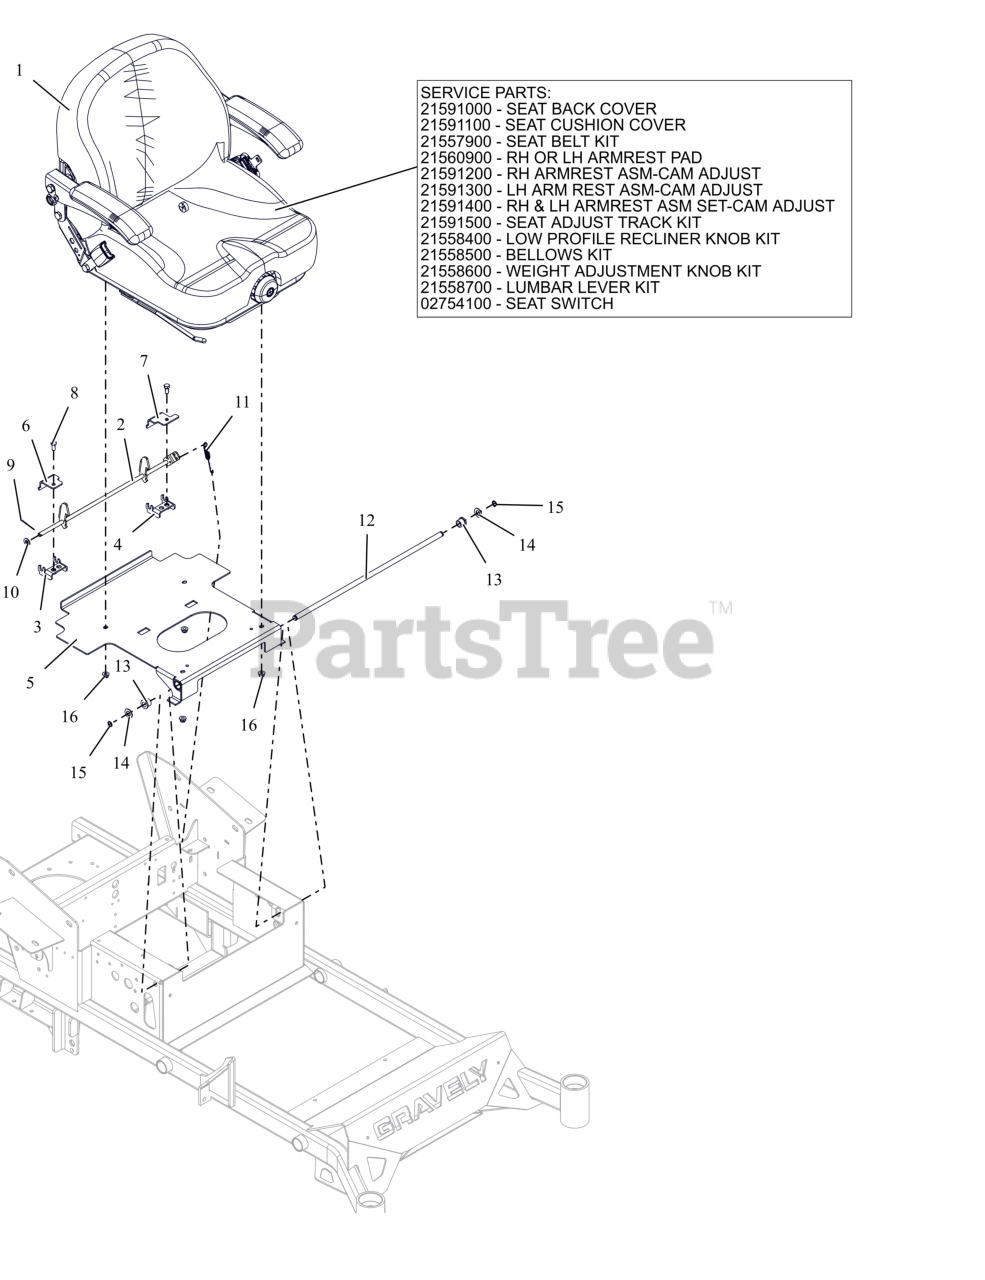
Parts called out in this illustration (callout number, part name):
1	SEAT- FULL SUSPENSION
1	SEAT BACK COVER
1	SEAT CUSHION COVER
1	KIT, SEAT BELT
1	PAD, ARMREST RH OR LH (HARD)
1	RH ARMREST ASM - CAM ADJUST
1	LH ARM REST ASM - CAM ADJUST
1	RH & LH ARMREST ASM SET - CAM ADJUST
1	SETA ADJUST TRACK KIT
1	KIT, LOW PROFILE RECLINER KNOB
1	KIT, BELLOWS
1	KIT, WEIGHT ADJUSTMENT KNOB
1	KIT, LUMBAR LEVER
1	SWITCH- SNAP MTG N.O.
2	PT100 SEAT LATCH WLDMT - BLACK
3	PT100 RH SEAT LATCH MNT WMT-BL
4	PT100 LH SEAT LATCH MNT WMT-BL
5	PT100 SEAT PLATE WLDMT - BLACK
6	PT100 RH TOP SEAT LATCH MNT-BL
7	PT100 LH TOP SEAT LATCH MNT-BL
8	BLT,HEX .31-18X.75 G5 ZCC
9	PIN, CTR .09X.750 EXTPRSQCT ZC120
10	WSHR,FLT .406X.812X.065 ZCC
11	SG-TENS .043X.44X3.31 WLD 5.8
12	SHAFT, PT100 SEAT PIVOT
13	BSHG, FLG .516X.750X.625X.937
14	WSHR, FLT .531X1.00X.063 ZCC
15	RG-RTNG-EXT .500X.050 (SNAP)
16	NUT,NYL-FLG .31-18 GF ZCC
